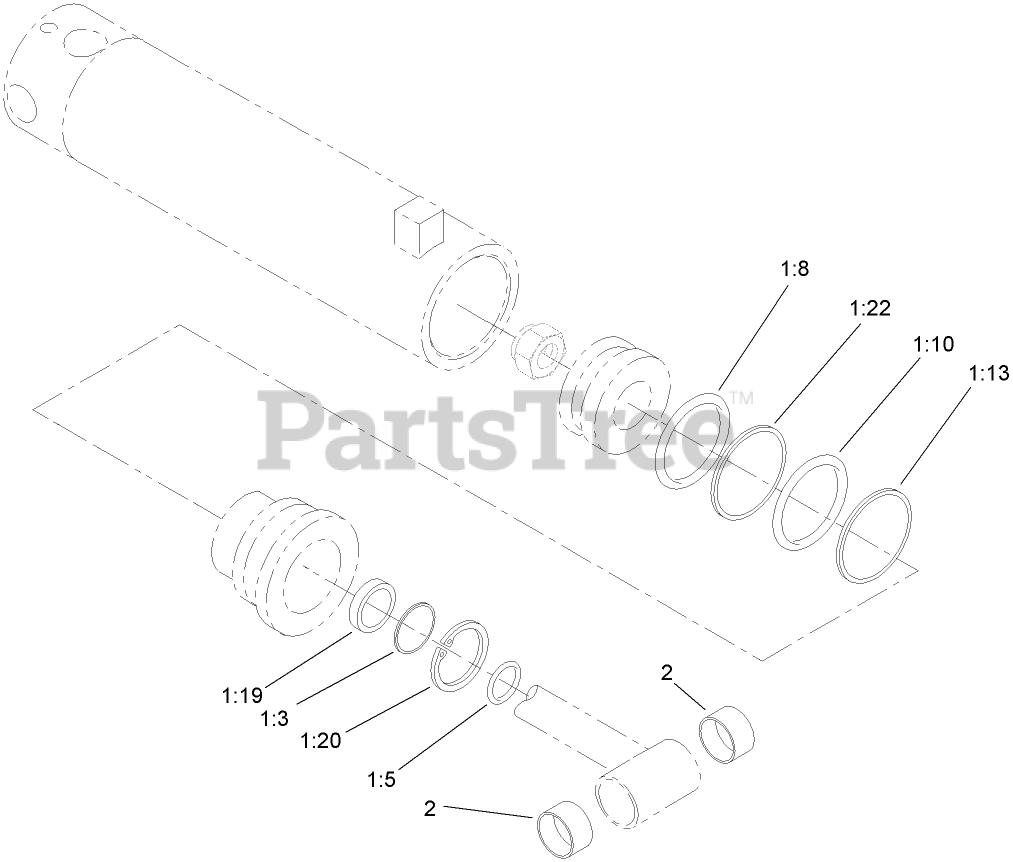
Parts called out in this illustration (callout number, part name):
1	CYLINDER SEAL KIT
1:3	Seal-Wiper
1:5	O-Ring
1:8	O-Ring
1:10	O-Ring
1:13	Ring-Backup
1:19	Seal-Rod
1:20	RING-Retaining
1:22	RING-Piston
2	BUSHING
